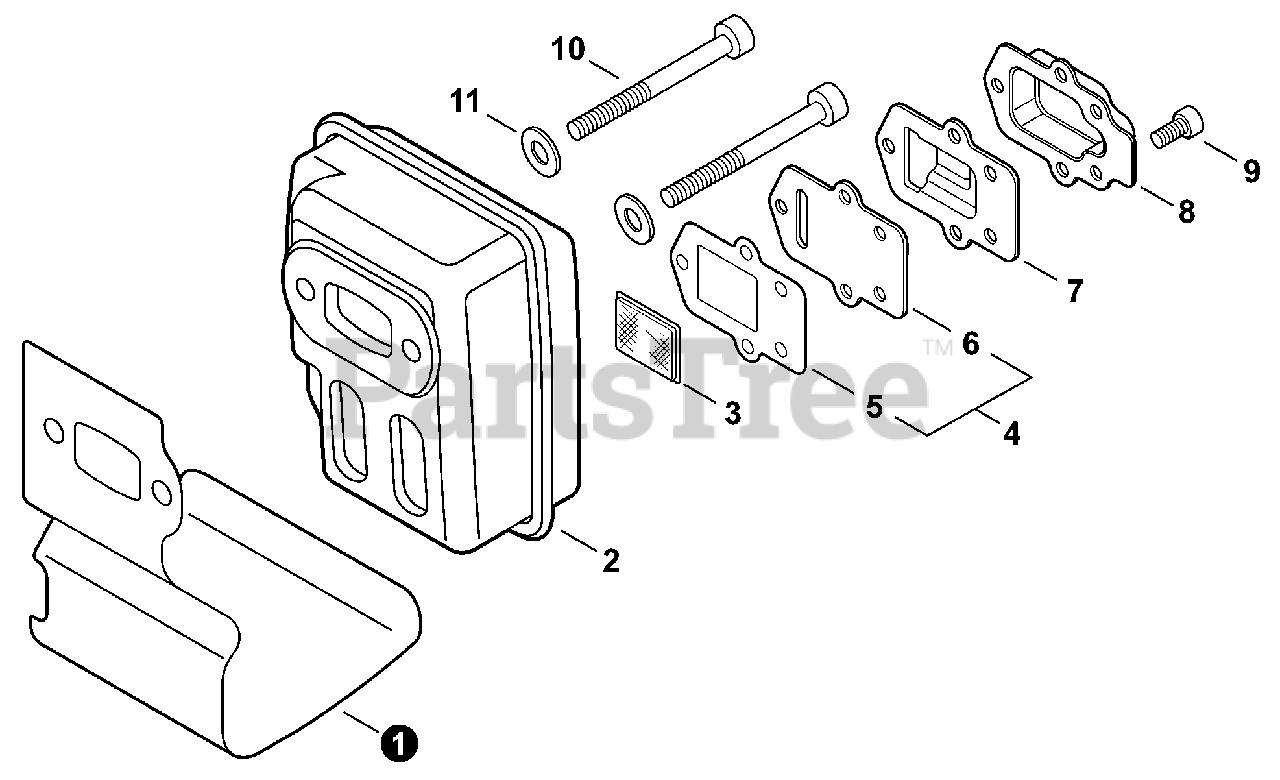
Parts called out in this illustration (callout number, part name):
1	HEAT SHIELD, EXHAUST
2	MUFFLER
3	SCREEN, SPARK ARRESTER
4	GASKET KIT, EXHAUST
5	GASKET, EXHAUST
6	GUIDE, EXHAUST
7	GUIDE, EXHAUST
8	OUTLET, EXHAUST
9	BOLT, TORX 4×8
11	WASHER 5.5×12×0.8
